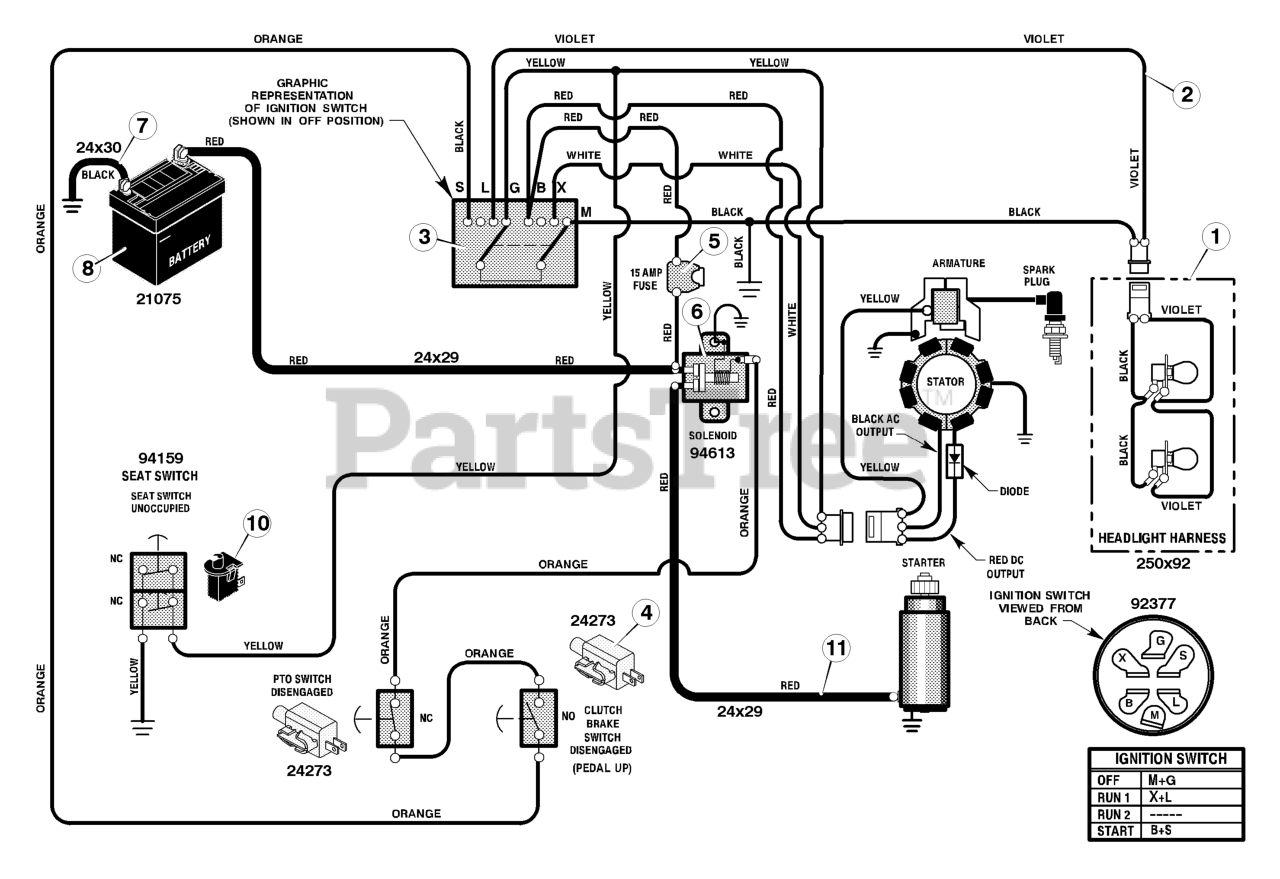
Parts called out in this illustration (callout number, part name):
1	Harness, Light Wire
2	Harness, Chassis Wire
3	Switch, Ignition
4	Switch, Limit
6	Solenoid
7	Cable, Battery Ground
8	Battery
10	Switch, Seat Sensor
